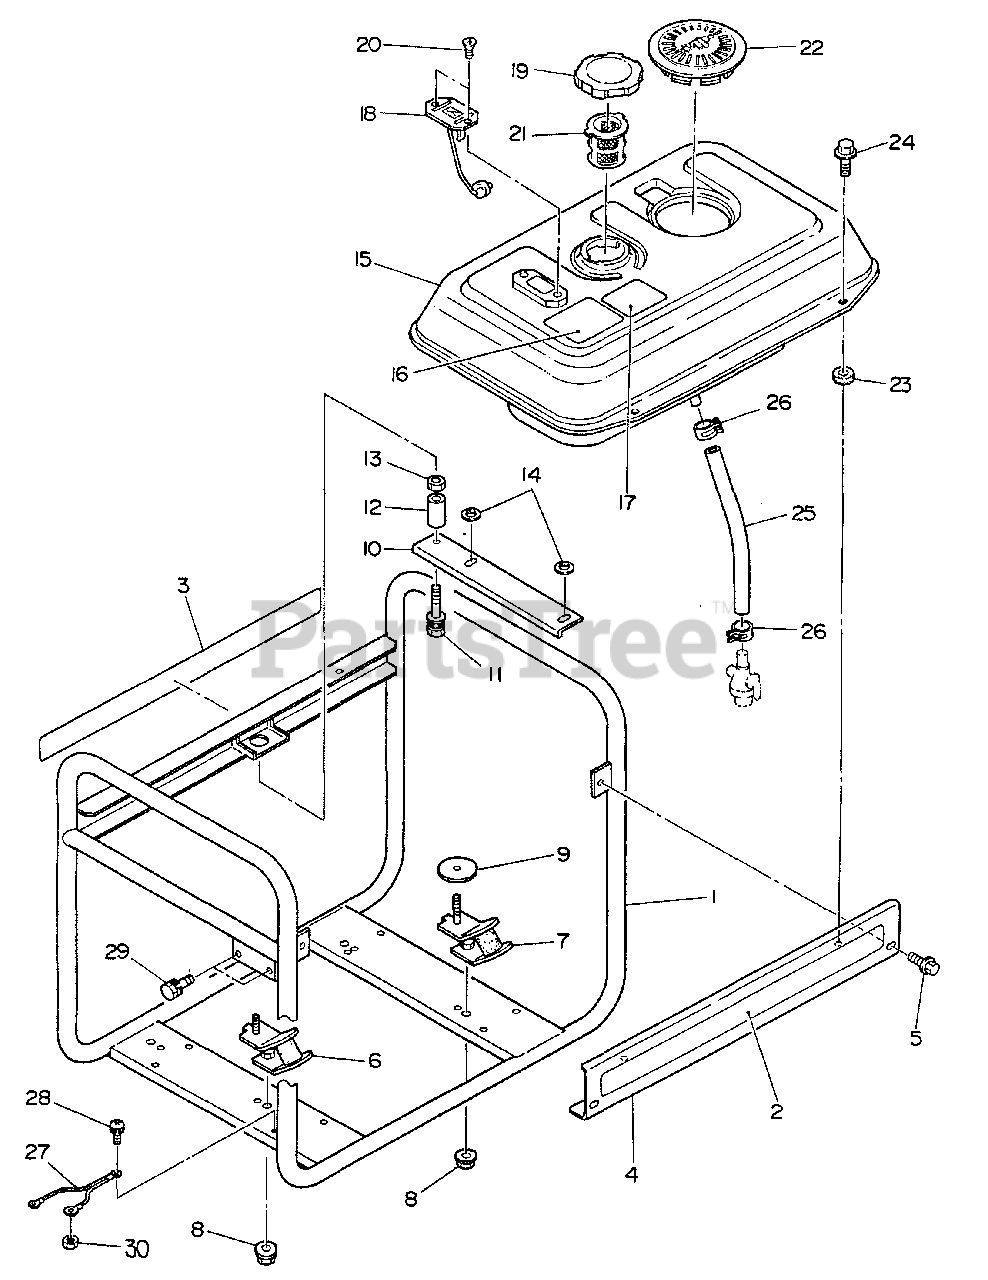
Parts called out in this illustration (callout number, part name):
1	PIPE FRAME, COMPL.
2	LABEL - MODEL EG-2400
3	LABEL - MODEL EG-2400
4	SIDE PLATE, COMPL.
5	BOLT - FLANGE
6	MOUNT, RUBBER
7	MOUNT, RUBBER
8	NUT, FLANGE
10	STOPPER PLATE
11	BOLT
12	SPACER
13	NUT
14	WASHER
15	FUEL TANK ASSY
16	LABEL - CAUTION -- OPERATION
17	LABEL - DANGER
18	FUEL GAUGE, COMPL.
20	SCREW
21	FILTER, FUEL
22	PLUG COVER
23	RUBBER WASHER
24	BOLT, FLANGE
25	RUBBER PIPE (11.5×17.5×230 MM)
26	CLAMP, HOSE
27	LEAD - GROUND
28	SCREW
29	BOLT
30	NUT
